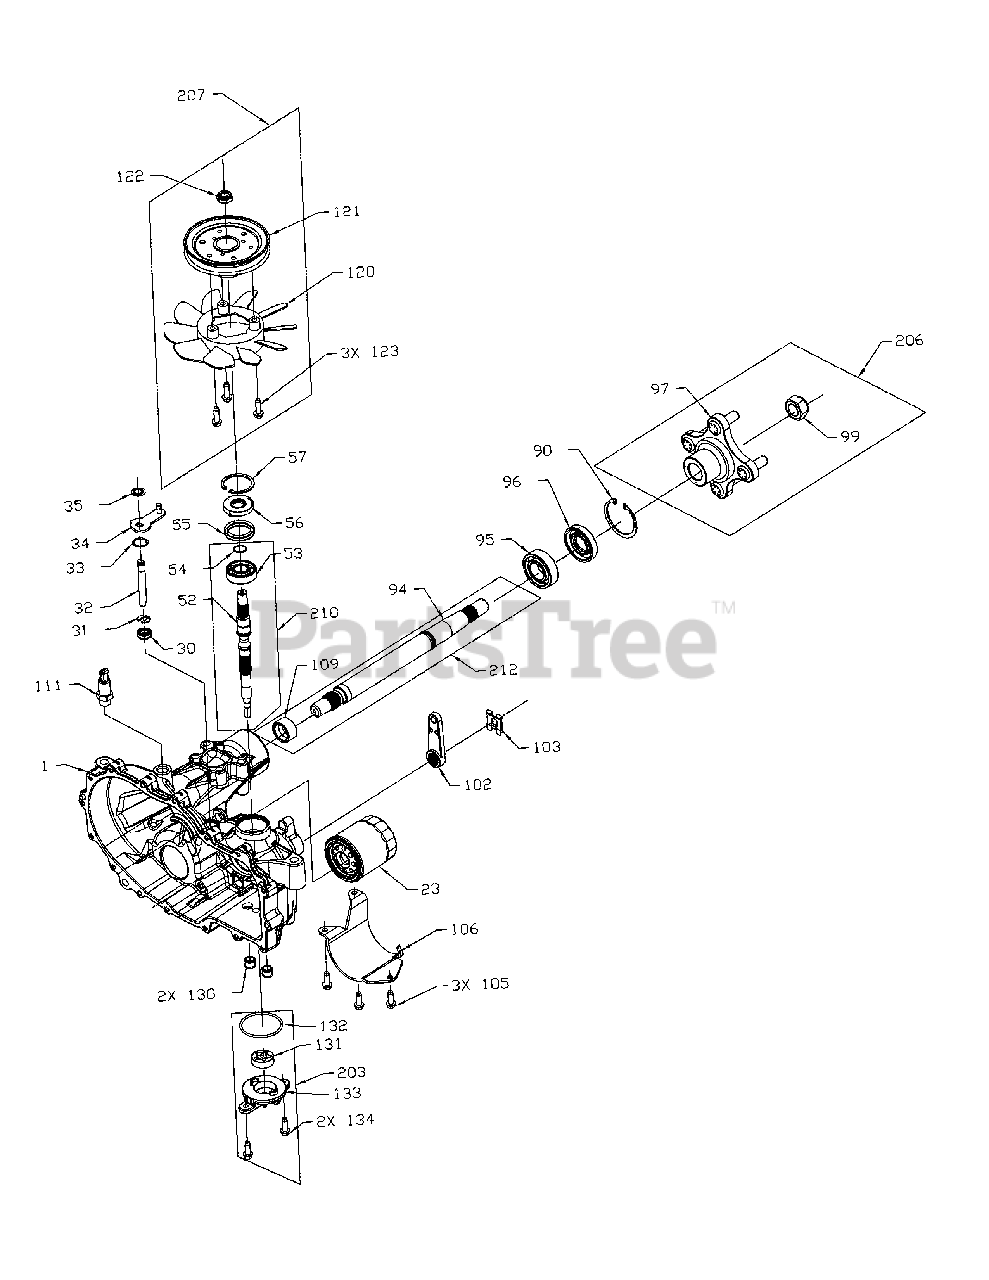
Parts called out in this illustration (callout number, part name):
1	Kit, Housing Main LH Chrg (includes
1	Housing, Main LH Chrg
1	Bushing .624 x .719 x .562
1	Brg, Jrnl .86 x .98 x .79
1	Pin .25 x .375
2	Kit, Cover Side LH Cntl (includes
2	Cover, Side LH Cntl
2	Bushing .624 x .719 x .562
2	Brg, Jrnl .86 x .98 x .79
7	HFHCS 1/4-20 x 1.25''
10	O-Ring 111.103 x .424
11	Plug 9/16/18 (Metal)
20	Center Section, LH Chrg
22	Plate, Bypass
23	Filter, Oil
24	Shock Valve
26	Seal, Plug 1.250 x .250
27	HFHCS 3/8-16 x 1.5 (Patch)
30	Seal, Lip .375 x .75 x .25
31	Ring, Ret .375 External
32	Rod, Bypass
33	Ring, Ret .750 Internal
34	Arm, Bypass
35	Ring, Rtng .375 Ext
40	Trunnion, Swashplate
41	Seal, Lip 18 x 32 x 7
44	Arm, Control
45	Washer .34 x .88 x .06
46	TWHCS 5/16-24 x 1.00 (Patch)
52	Shaft, Input
53	Brg, Ball 17 x 40 x 12 Open 6203
54	Ring, Ret Wire .561 ID
55	Washer 1.23 x 1.56 x .04
56	Seal, Lip 17 x 40 x 7
57	Ring, Ret 2.06 Internal
60	Bearing, Thrust
64	Cylinder Block Assembly 16cc
65	Bearing, Thrust Ball 30 x 52 x 13
69	Block 7 Piston Assembly
70	Washer .63 x 1.0 x .05
71	Ring, Ret 62 External
72	Gear, 16T
73	Shaft, Motor
74	Washer .72 x 1.16 x .04
80	Washer .5 x 1.0 x .03
81	Gear, 43T
82	Gear, 11T
83	Jack Shaft (Pin)
90	Ring, Ret 2.06 Internal
91	Gear, 54T
92	Spacer, .750 x 1.000 x .257
93	Bearing Ball .75 x 40 x 12
94	Shaft, Axle
95	Bearing Ball 1.0 x 52 x 15 Open 6205M
96	Seal, Lip TC4
97	Hub, 4 Stud (3.56 Taper)
99	Nut, Hex Lock 3/4-16
100	Pawl, Brake
101	Shaft, Brake
102	Handle, Brake
103	Clip, Retaining
105	HFHCS 1/4-20 x .75
106	Guard, Filter - LH
109	Spacer, .91 x 1.02 x .625
111	Fitting, Str 9/16-18 SAE .5 Barb
120	Fan, 7'', 10 Blade
121	Pulley 4.5 Inch
122	Nut, Hex Lock 1/2-20 Nylon
123	HFHCS 1/4-20 x .75
130	Tube, Connecting
131	Gerotor Assembly (1.6 cc/rev)
132	O-Ring, -137, 0.103 x 2.050
133	Cover, Charge Pump
134	HFHCS 1/4-20 x .75
135	Ball, Steel 7/16''
136	Spring relief .42 x .250
137	Pin, Spring .125 x .875
140	Spacer, .320 x 1.005 x .179
141	Arm, Neutral Left
142	SHCS 5/16-24 x 1 (Patch)
145	Assembly, RTN
146	Washer, .343 x 1.500 x .062
147	Spring, Extension .57 x 2''
148	Bracket Damper
200	Kit, Seal
201	Kit, Center Section, LH Chrg
202	Kit, Chrg Relief
203	Kit, Charge
206	Kit, Hub 4 Bolt
207	Kit, Fan/ Pulley
209	Hub Puller, 4 Bolt
210	Kit, Input Shaft
211	Kit, RTN Bidirectional LH
212	Kit, Axle Shaft
